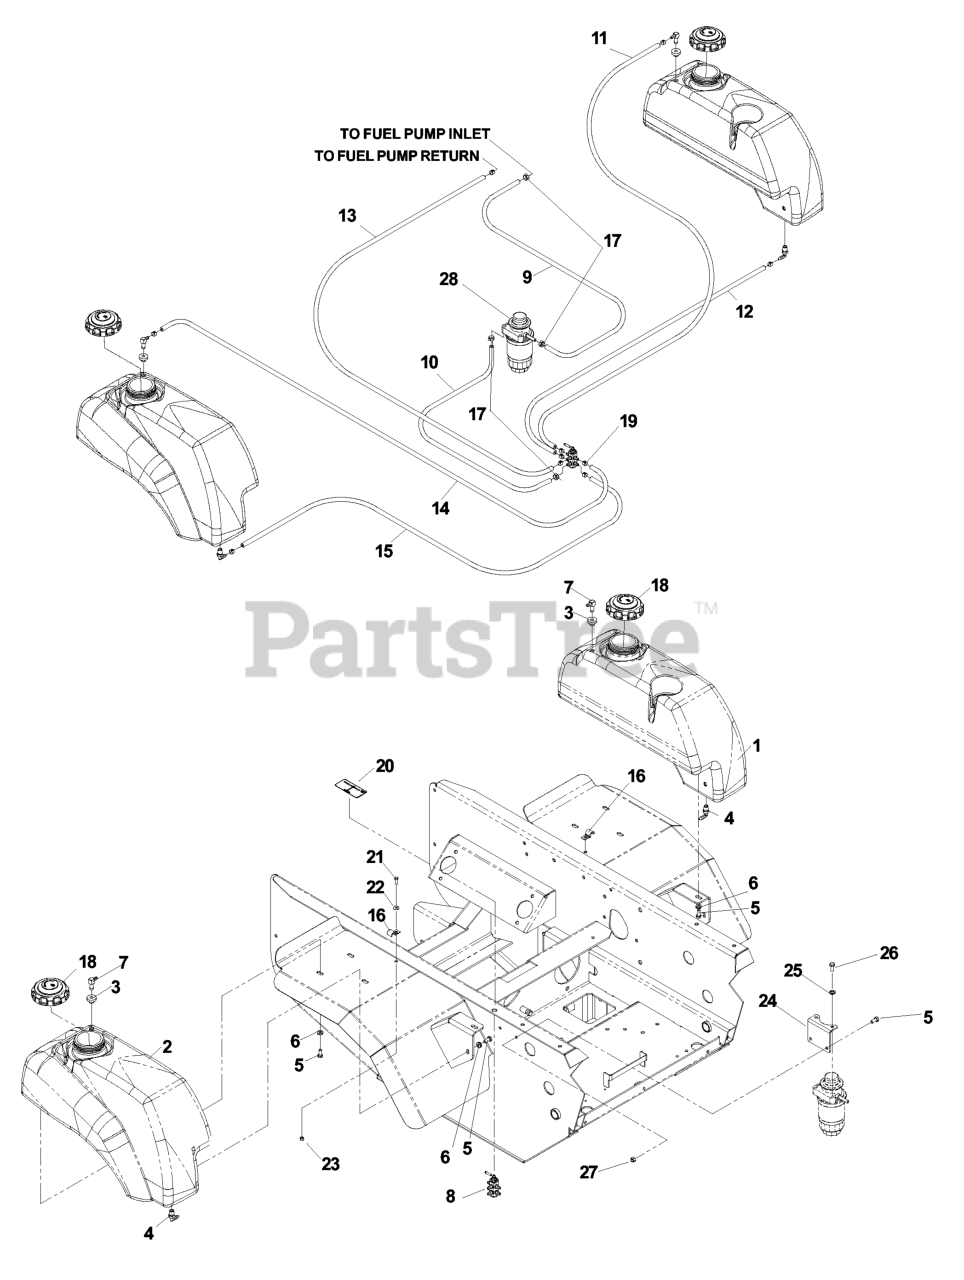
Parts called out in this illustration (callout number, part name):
1	FUEL TANK DIESEL LT
2	FUEL TANK DIESEL RT
3	RUBBER GROMMET
4	HOSE BARB 90 DEGREE
5	HCS 5/16C X 3/4
8	FUEL VALVE
9	FUEL LINE 38"
10	FUEL LINE 35"
11	FUEL LINE 79"
12	FUEL LINE 57"
13	FUEL LINE 54"
14	FUEL LINE 34"
15	FUEL LINE 13"
18	TANK CAP - DIESEL
19	HOSE CLAMP
20	FUEL VALVE DECAL
21	HCS 1/4C X 3/4 HCS
22	WASHER 1/4 FLAT
23	NUT.1/4-20.HEX.NYLOC.ZD
24	MOUNTING BRACKET
25	WASHER.LOCK.HVY.HLCL.SPR.5/16
27	NUT 5/16 NYLOC
28	FUEL FILTRATION SYSTEM
